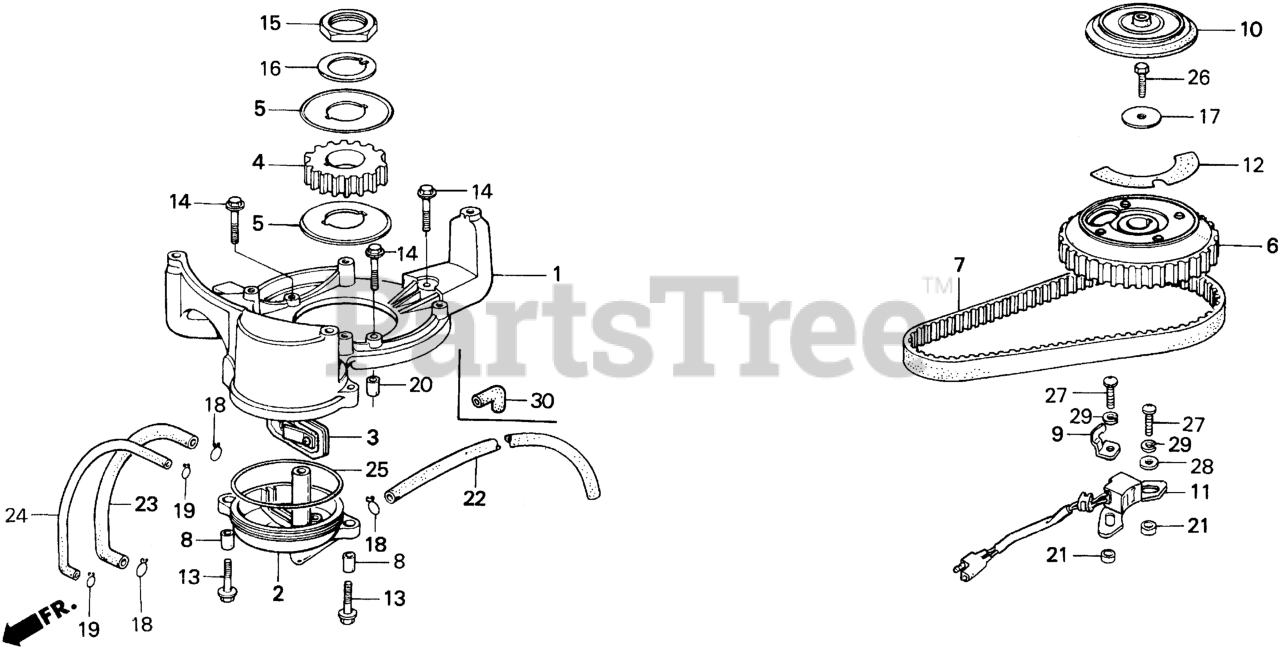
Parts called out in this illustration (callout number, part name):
1	CASE, STARTER *NH8* (DARK GRAY)
2	COVER, BREATHER
3	BODY, VALVE
4	PULLEY, TIMING
5	FLANGE, TIMING PULLEY
6	PULLEY, CAMSHAFT
7	BELT, TIMING
8	COLLAR A, DISTANCE
9	PLATE, WIRE CLAMP
10	COVER, POINT
11	COIL ASSY., PULSER (NOT AVAILABLE)
12	MARK, POINT
13	BOLT, FLANGE (6X22)
14	BOLT, FLANGE (6X28)
15	NUT, LOCK (24MM)
16	WASHER, LOCK (24MM)
17	WASHER, WHEEL (6MM)
18	CLIP, TUBE (B12)
19	CLIP B7, TUBE
20	PIN, DOWEL (8X10) Use up to Engine SN 2056819.
21	PIN, DOWEL (7X4.5)
22	TUBE B, BREATHER (NOT AVAILABLE)
23	TUBE C, BREATHER
24	TUBE, OIL RETURN
25	O-RING (62X2.5)
26	BOLT, HEX. (6X22)
27	SCREW, PAN (5X14)
28	WASHER, PLAIN (5MM)
29	WASHER, SPRING (5MM)
